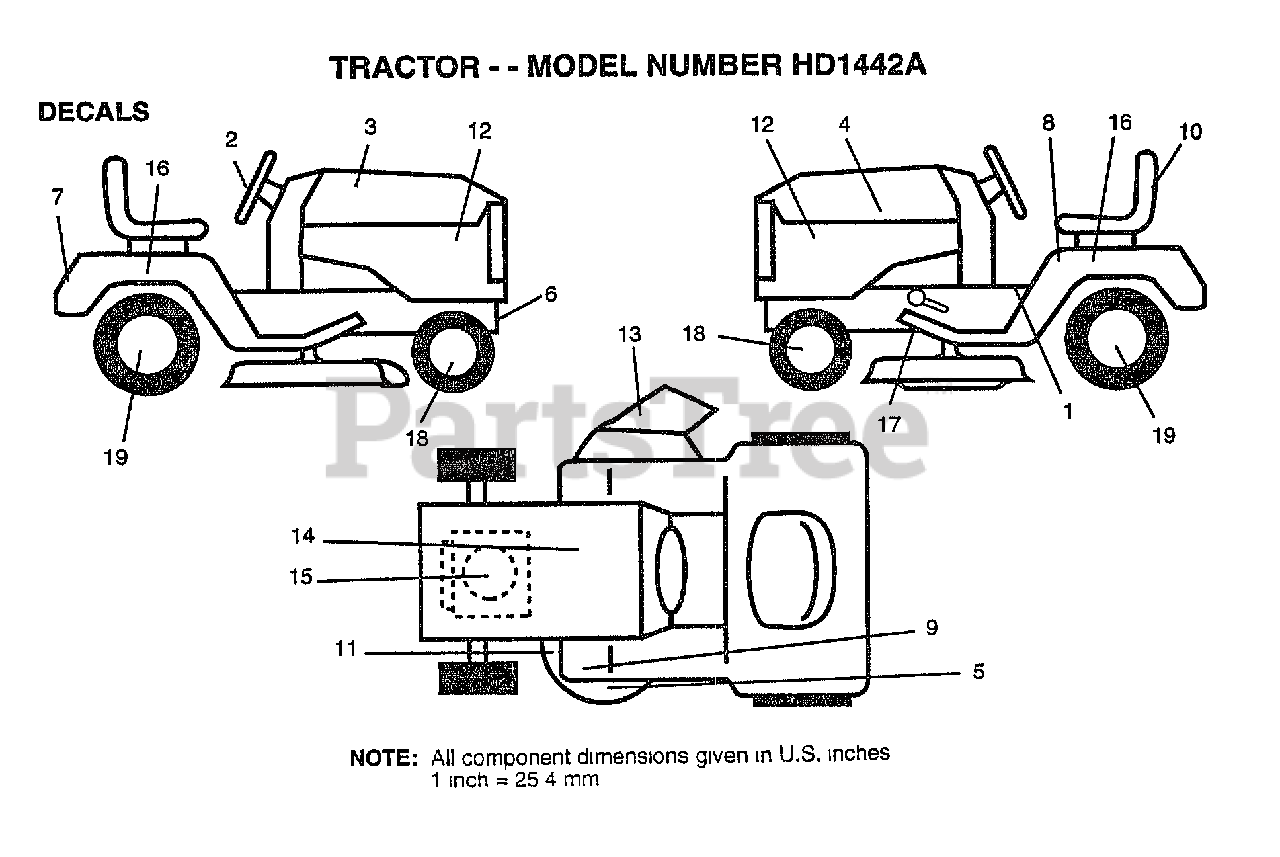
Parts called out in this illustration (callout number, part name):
1	DECAL.SADDLE.INST
2	DECAL.INST.WHL.ST
3	DECAL.HD.RH.14HP.
4	DECAL.HD.LH.14HP.
5	DECAL.DECK.MULCH.
6	DECAL.FENDER.HDEP
7	DECAL.FENDER.HDEP
8	DECAL CAUT FEND
9	DECAL CLUT/BRAKE
10	DECAL.SEAT.WEED.
11	DECAL.SCH.PRIM.42
12	DECAL.PNL.SD.HDEP
13	"DECAL, WARNING"
14	DECAL.BATRY.3-3908
15	DECAL.PARTS.ONAN
16	DECAL.FEND.QUICKS
17	DECAL.SCH.DRV.42
18	DECAL.HUBCAP.6.HD
19	"DECAL.HUBCAP.8"""
